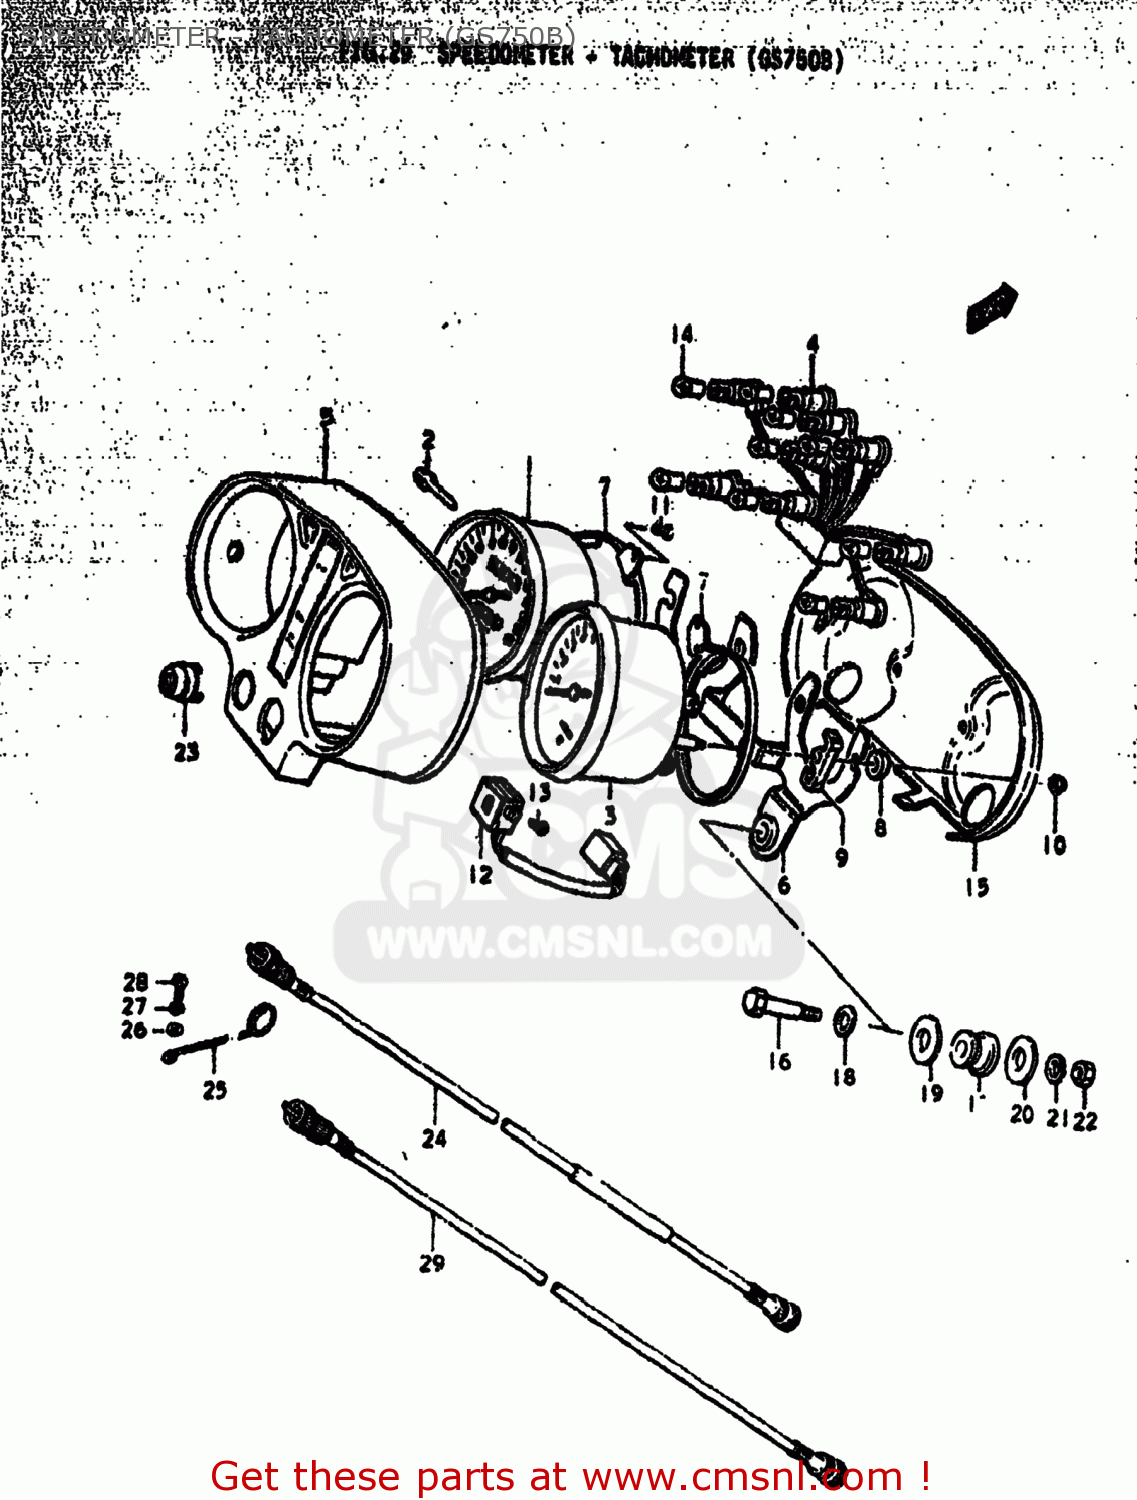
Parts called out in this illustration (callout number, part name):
1	SPEEDOMETER ASSEMBLY
2	KNOB
3	TACHOMETER
4	SOCKET,METER
5	CASE,METER
6	BRACKET,COMBINATION METER
7	PLATE,METER,UNDER
8	CUSHION,METER (A)
9	CUSHION,METER (B)
10	NUT
11	SCREW
12	INDICATOR ASSEMBLY,GEAR POSITION
14	BULB(12V3.4W,STANLEY,A72A)
15	PLATE,UNDER
16	BOLT(8X39.2)
17	CUSHION,METER
18	WASHER
19	WASHER
20	WASHER
21	LOCK WASHER
22	NUT
23	CAP,SPEED WARNER LAMP HOLE
24	CABLE ASSEMBLY,SPEEDOMETER
25	GUIDE,SPEEDOMETER CABLE
26	WASHER 6MM
27	LOCK WASHER
28	BOLT, UPPER
29	CABLE ASSEMBLY,TACHOMETER
